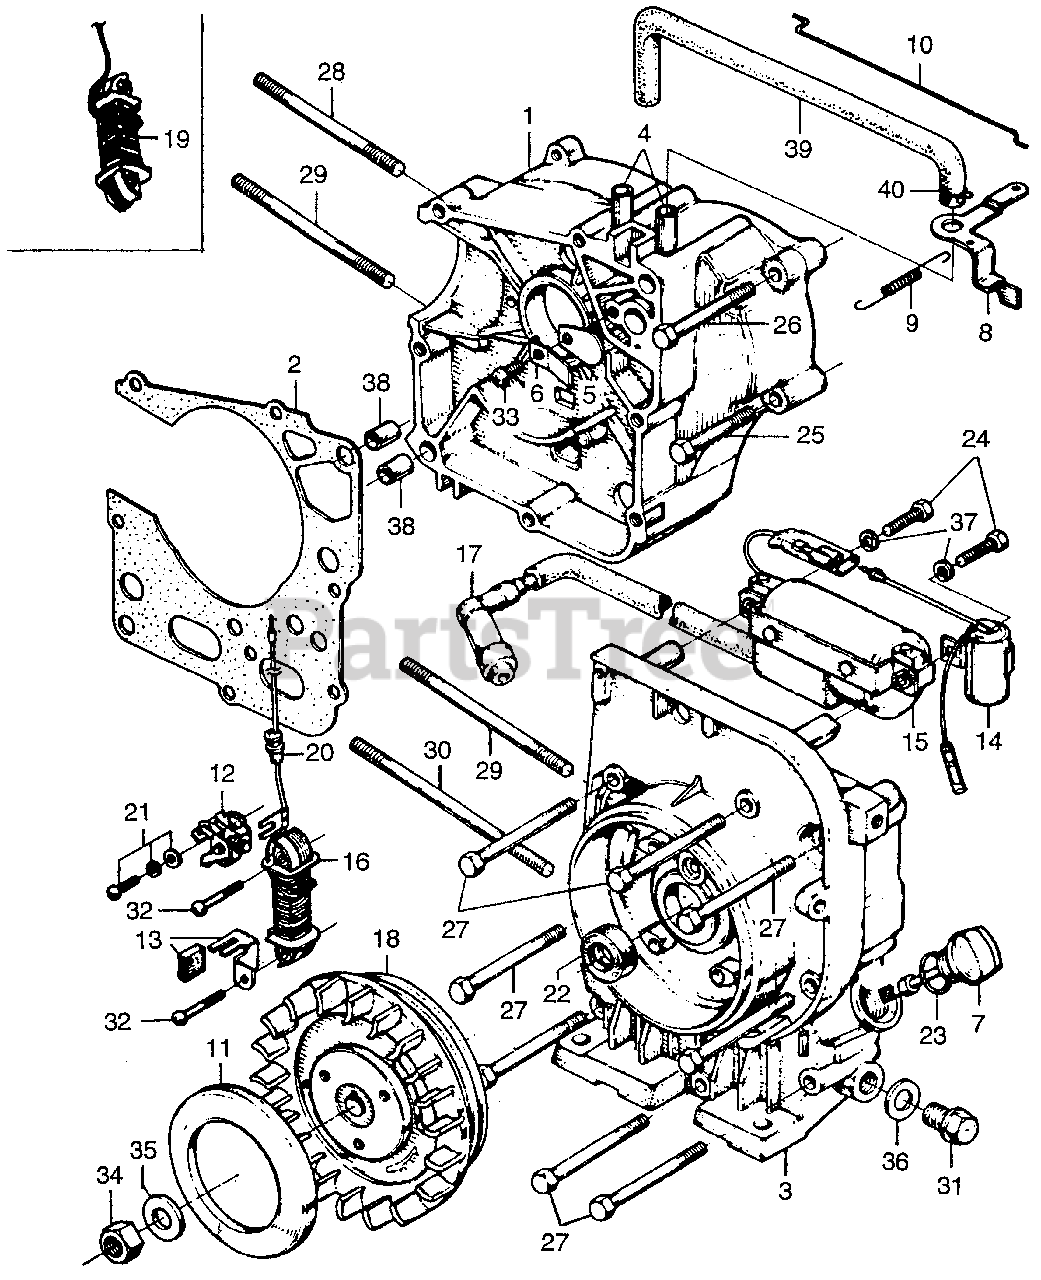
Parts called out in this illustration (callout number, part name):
1	CRANKCASE, R.
2	GASKET, CRANKCASE (NOT AVAILABLE)
3	CRANKCASE, L.
4	JOINT, BREATHER (NOT AVAILABLE)
5	VALVE, BREATHER
6	STOPPER, BREATHER
7	CAP, OIL FILLER (NOT AVAILABLE)
8	LEVER, CHOKE
9	SPRING, CHOKE LEVER (NOT AVAILABLE)
10	ROD, CHOKE (NOT AVAILABLE)
11	COVER, SEAL
13	FELT, OIL (DENSO)
15	COIL, IGNITION (NOT AVAILABLE)
15	COIL, IGNITION
16	COIL, IGNITION (NOT AVAILABLE)
17	CAP ASSY., NOISE SUPPRESSOR (NICHIRIN)
18	FLYWHEEL (NOT AVAILABLE)
19	COIL ASSY., EXCITER
19	COIL ASSY., EXCITER (NOT AVAILABLE)
20	GROMMET, WIRE
21	SCREW, STOP (NOT AVAILABLE)
22	OIL SEAL (15X25X6)
23	O-RING (16MM)
23	O-RING (15.8X2.4) (SHOWA)
24	BOLT, HEX. (5X25)
25	BOLT, HEX. (6X32)
26	BOLT, HEX. (6X45)
27	BOLT, HEX. (6X56)
27	BOLT, HEX. (6X56) (NOT AVAILABLE)
28	BOLT, STUD (6X80) (NOT AVAILABLE)
29	BOLT, STUD (6X90)
30	BOLT, STUD (6X116)
31	BOLT, DRAIN PLUG (12MM)
32	SCREW, PAN (4X20)
33	SCREW, PAN (5X8)
34	NUT, HEX. (10MM)
35	WASHER (10MM)
36	WASHER, DRAIN PLUG (12MM)
37	WASHER, SPRING (5MM)
38	PIN A, DOWEL (10X16)
39	TUBE (7X224) (NOT AVAILABLE)
39	TUBE (7X224)
40	CLIP, TUBE (B12)
40	CLIP, TUBE (C11)
